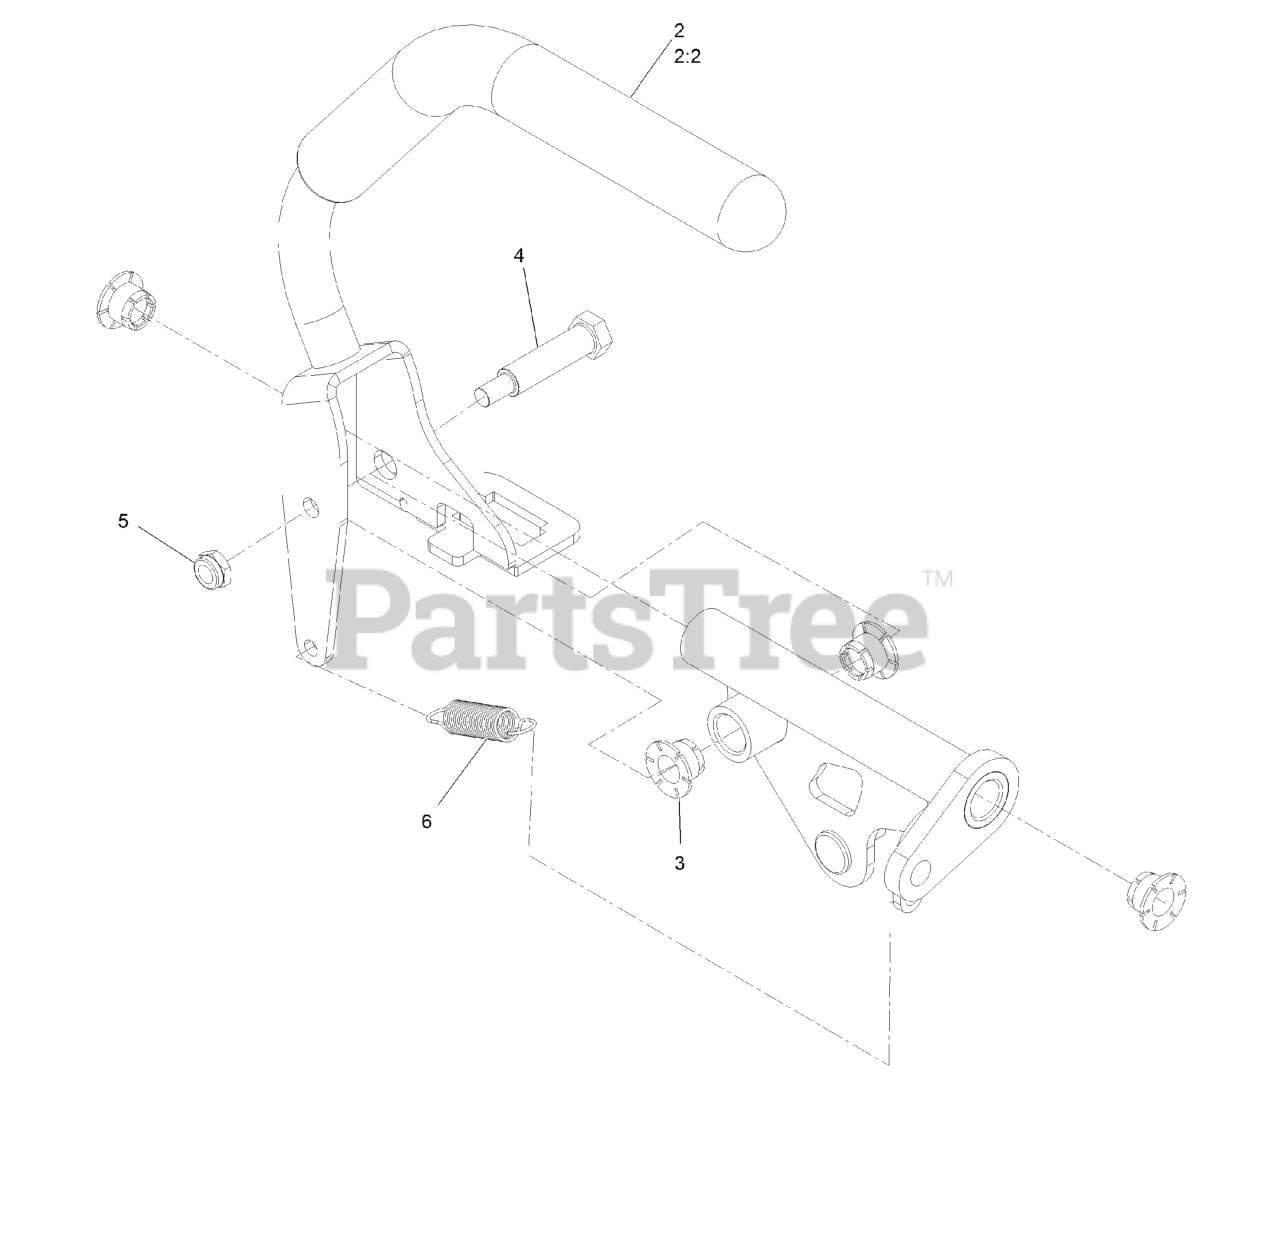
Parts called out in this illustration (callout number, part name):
2	ASM, LT CONTROL LEVER W/ GRIP
2:2	GRIP, DRIVE LEVER
3	BEARING, IGUS
4	BOLT-SHOULDER
5	NUT-LOCK, NI
6	SPRING-EXTENSION
